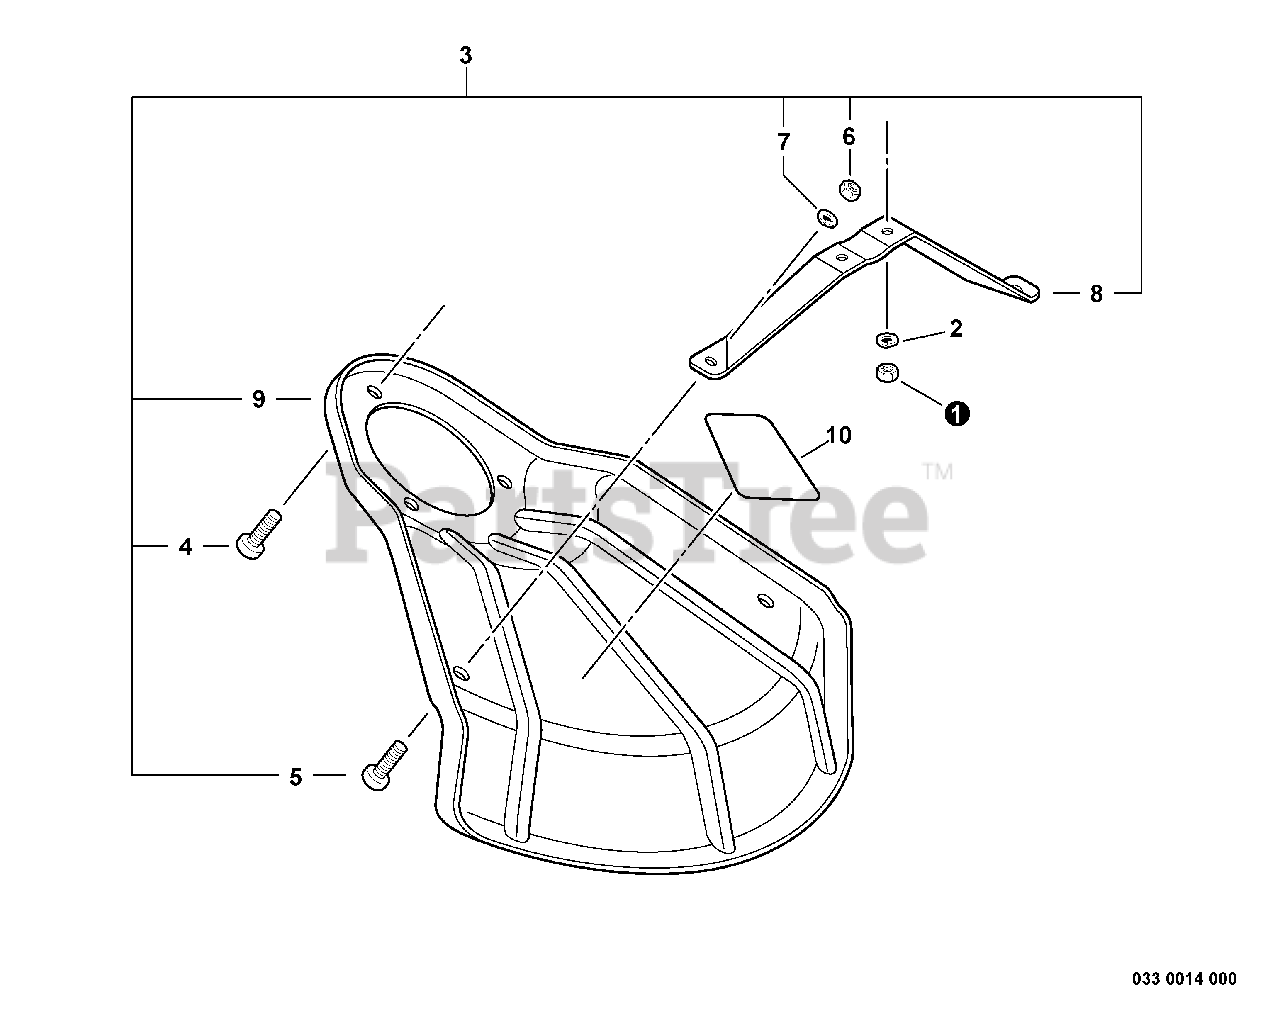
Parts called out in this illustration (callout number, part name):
2	LOCKWASHER - 5
3	DEBRIS SHIELD KIT - METAL
4	SCREW - 5X10
5	SCREW - 5X8
7	LOCKWASHER - 5
8	BRACKET, SHIELD
9	SHIELD, DEBRIS - METAL
10	LABEL - DANGER
